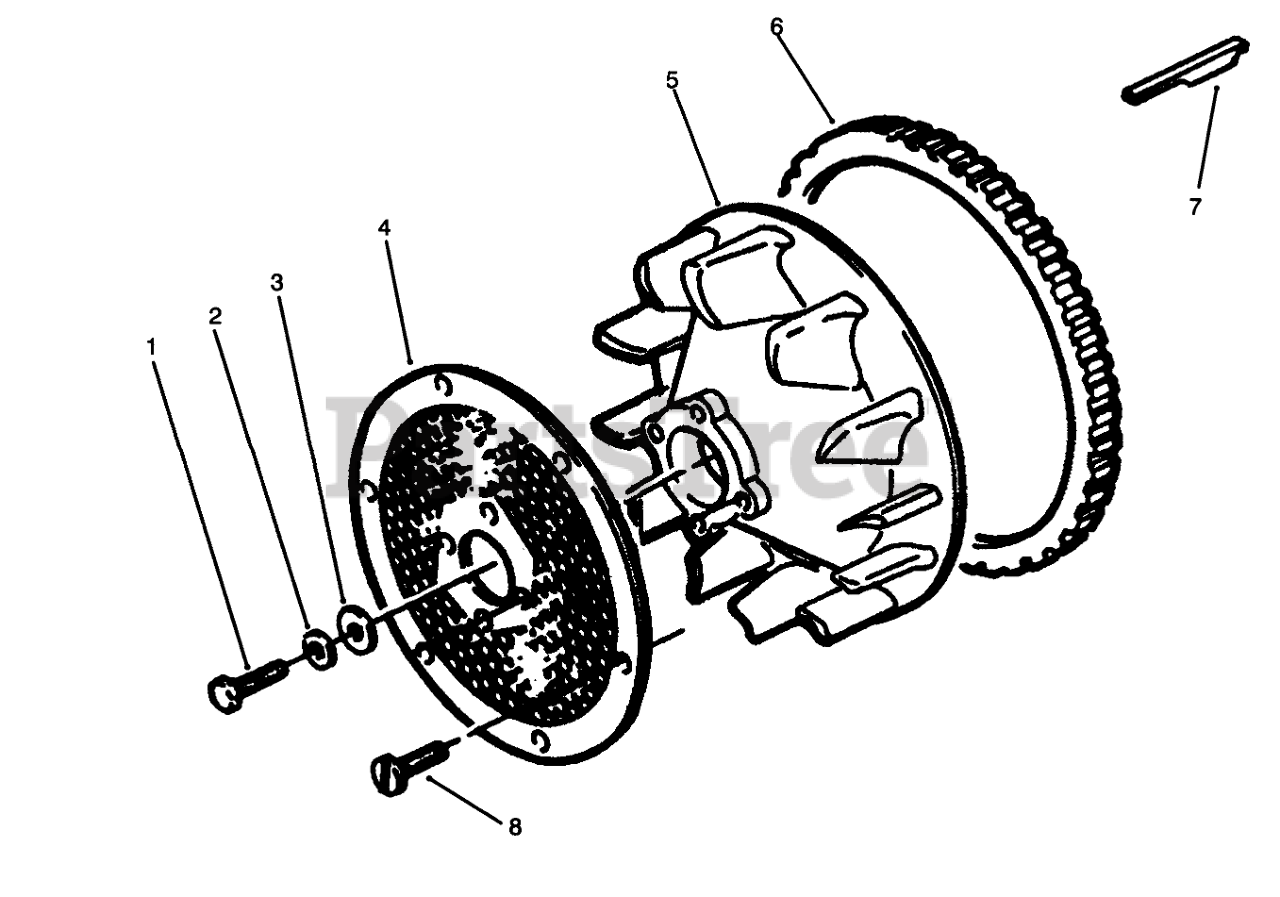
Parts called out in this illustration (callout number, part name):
1	SCREW
2	WASHER-FLAT
3	WASHER-FLAT
4	Screen
5	Flywheel (Incl. Ref. #6)
7	KEY-FLYWHEEL
8	LOCK SCREW
